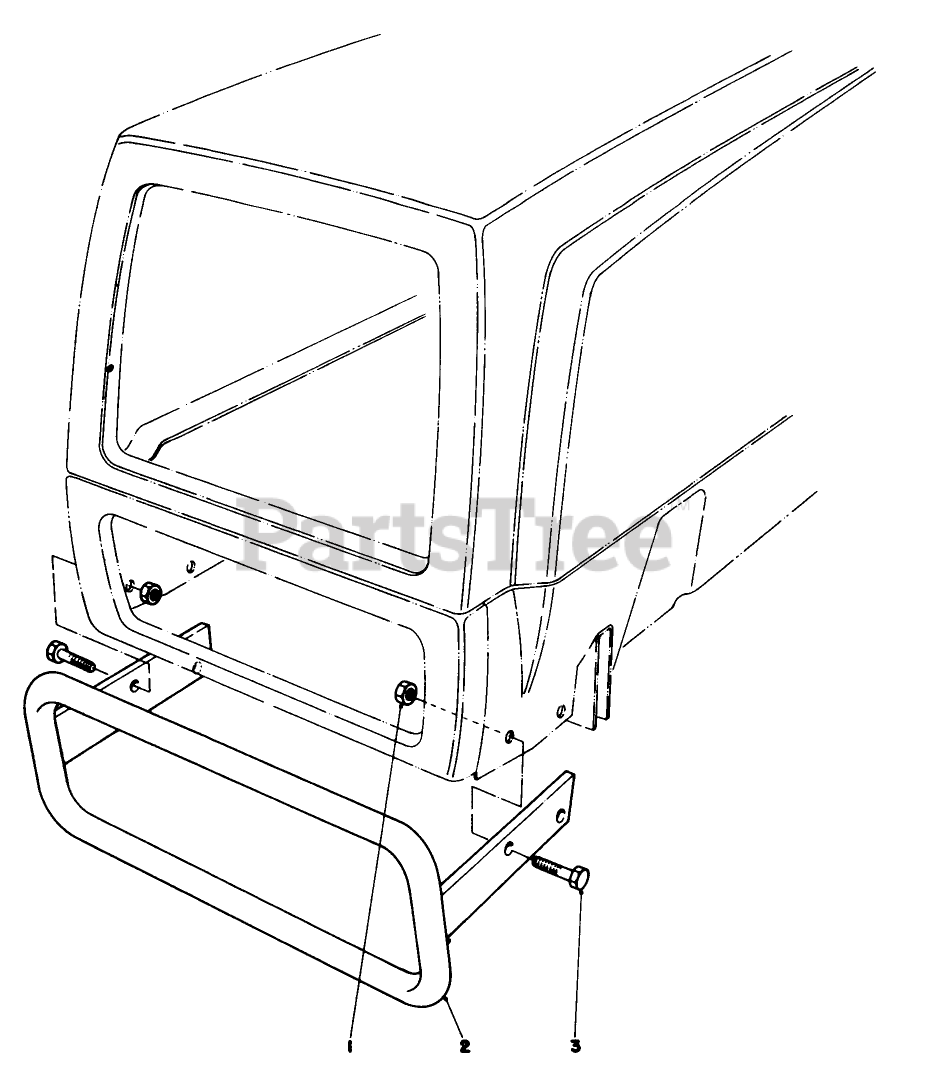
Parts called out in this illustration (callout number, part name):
1	NUT-LOCK, CONE
2	Bumper W.A.
3	SCREW-HH
